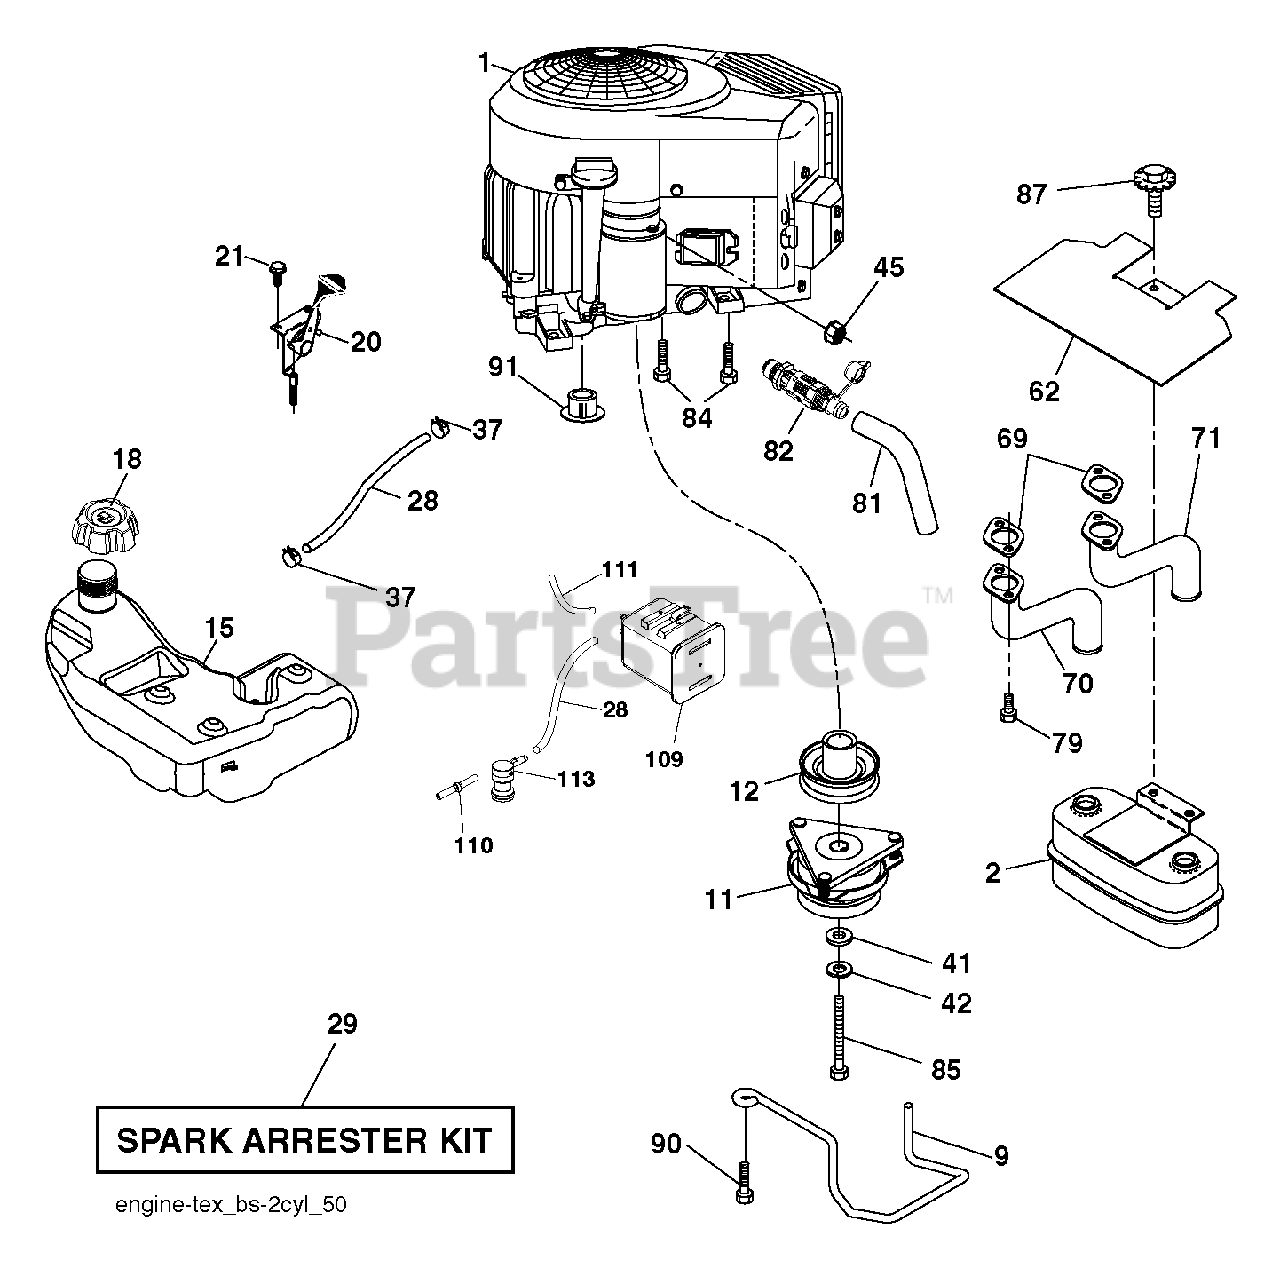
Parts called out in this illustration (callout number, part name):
2	MUFFLER.TWIN.CYL.LOW.TONE
9	KEEPER.BELT.ENGINE.4.2
11	CLUTCH.ELECTRIC.LT.48"*
12	PULLEY.ENGINE.TUFFTORQ
15	TANK.ASM.FUEL.3GA.CARB
18	RP CAP ASM
20	CONTROL.TH/CK.COBRA.B&S.TWN.
21	SCREW.#10 X 0.750.BOS
28	LINE.FUEL.64"REAR.EMIS
29	KIT.SPARK ARRESTOR 794945 B&S
37	HOSE CLAMP
42	LOCKWASHER
45	NUT
62	RP SHIELD HEAT MUFFLER
69	GASKET.MUFFLER
70	RP.EXHAUST.TUBE.LH.BS/TWIN
71	EXHAUST.TUBE.RH.BS/TWIN
79	SCREW.SOCKET.HEAD.5/16-18
81	TUBE, DRAIN OIL ASM.
82	VALUE.OIL.DRAIN
84	SCREW.3/8-16
85	BOLT HEX 7/16-20X4-1/4"
87	BOLT, 5/16-18 X 1 3/4
90	SCREW 3/8-16X1
91	BUSHING.1.375OD
109	CANNISTER, CARBON
110	VALVE.ASM.ANTI-SLOSH
111	RP PURGE LINE
113	VALVE.SLANT.CARTRDG.90 DEG.TEX
